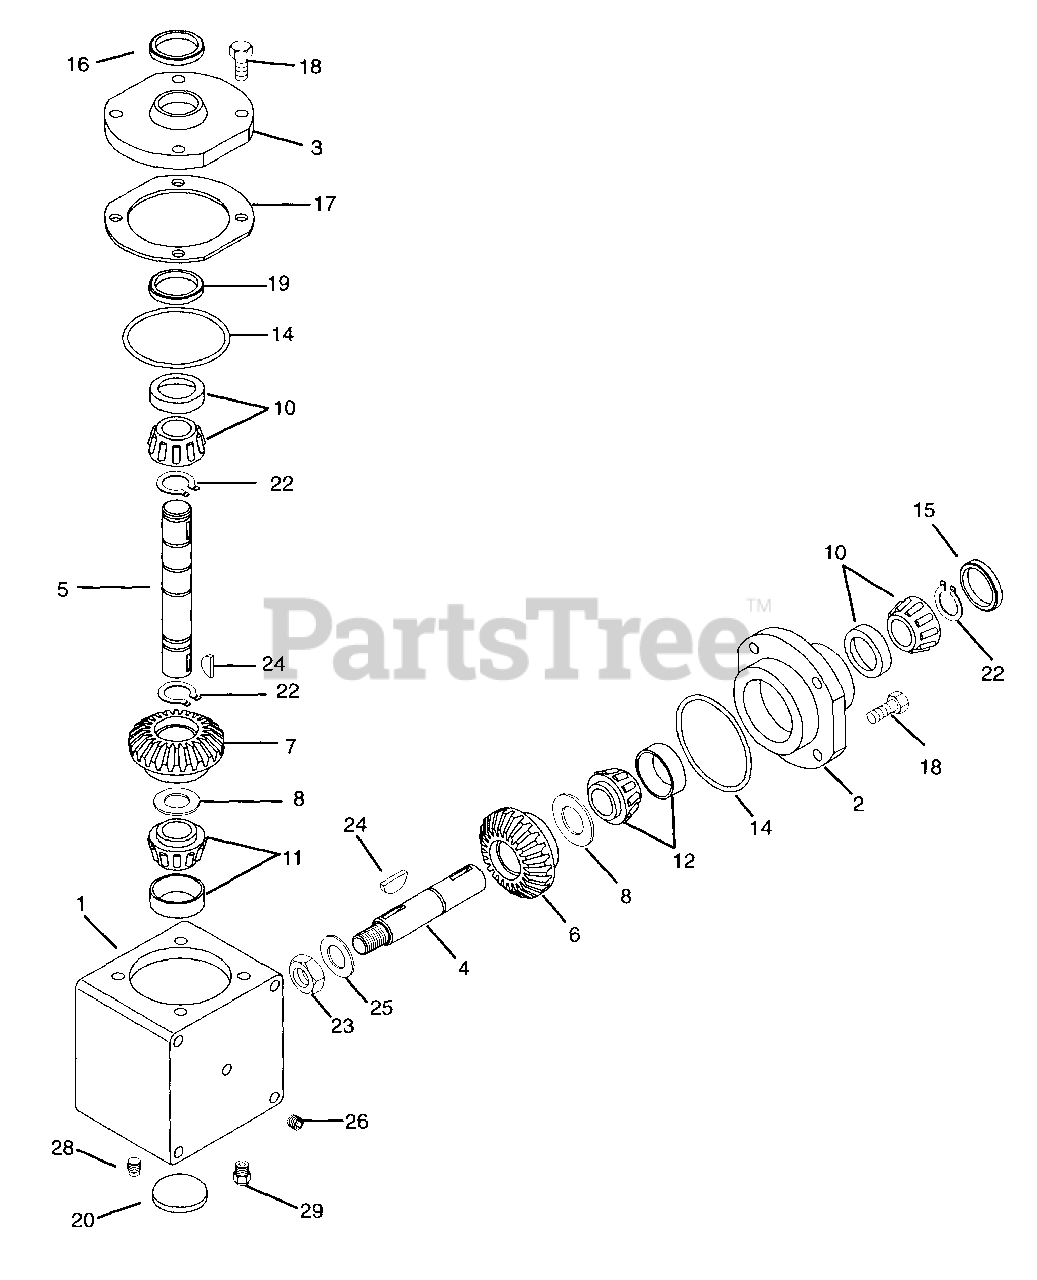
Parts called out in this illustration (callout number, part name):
1	Housing, Right Angle Drive
2	Cap, Retainer
3	Cap, Retainer
4	Shaft, Input (5.38" long)
5	Shaft, Output (7.89" long)
6	Gear, Spiral Bevel (25 teeth)
7	Gear, Spiral Bevel (26 teeth)
8	Shim (1-1/2" O.D. x 1-1/64" I.D. x .002 thick)
9	Shim (2.000" O.D. x 1.531" I.D.x.002 thick)
10	Bearing & Cup Assy.
11	Bearing & Cup Assy.
12	Bearing & Cup Assy.
14	"O" Ring
15	Seal, Oil
16	Seal, Oil
17	Shim, Cap Retainer
18	Screw, Hex, hd. sems, 5/16-18 x 1
19	Ring Load
22	Ring, Retaining
23	Jam Nut, 3/4-16
24	Key, Woodruff
25	Washer, Flat 1
26	Plug, Pipe, /14-18
28	Plug, Pipe, 1/8-27
29	Valve, Relief
